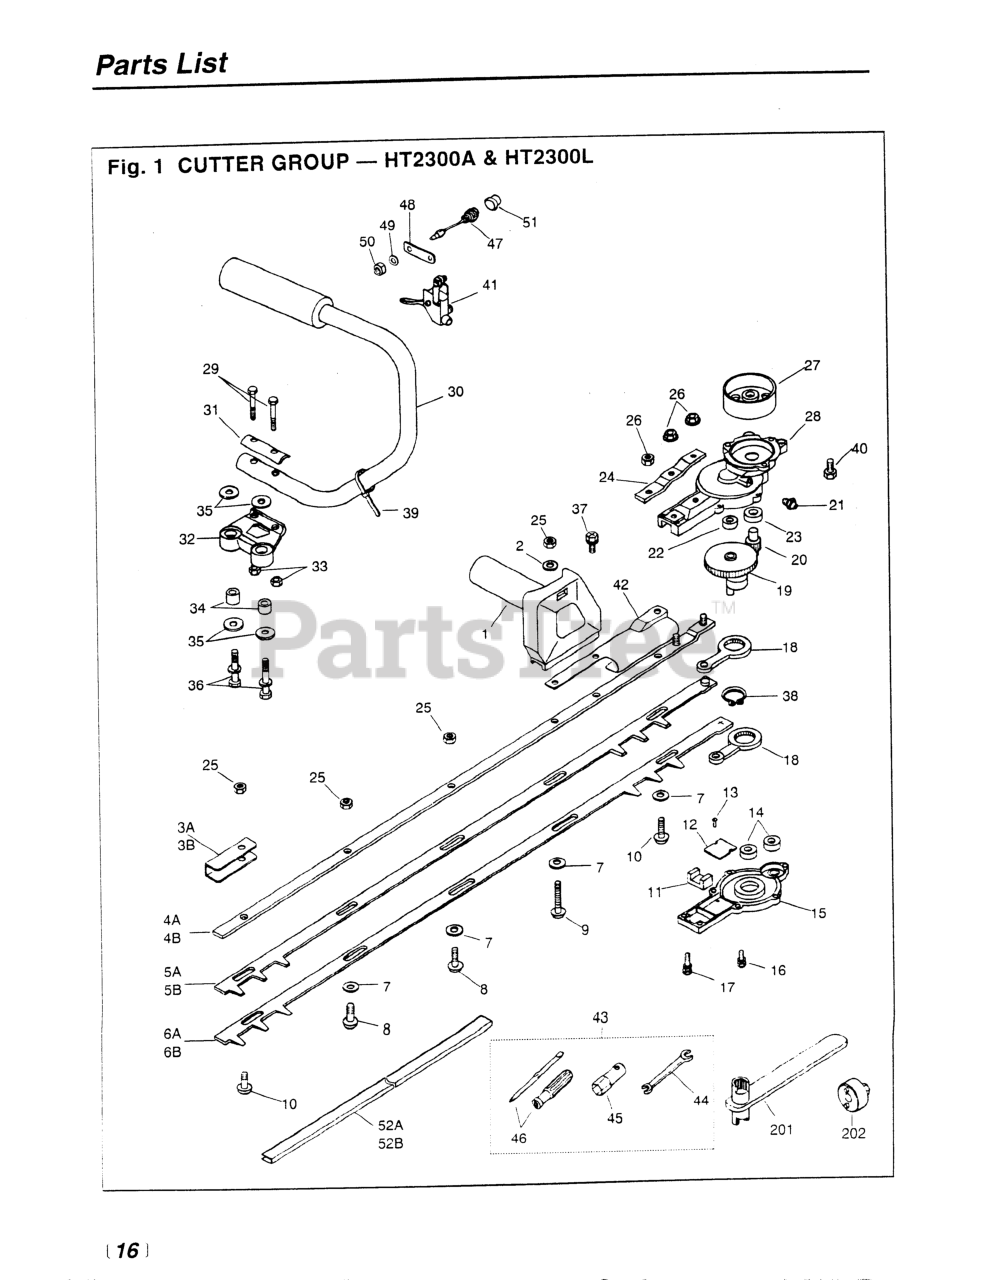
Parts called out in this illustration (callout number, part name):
1	HANDLE (RPLS -12100)
3B	REINFORCE
5B	BLADE, UPPER 40
6B	BLADE, LOWER 40
7	WASHER (RPLS 3873-11760)
11	FELT
12	PLATE
13	SCREW, M3 x 5
14	BEARING
15	CASE, LOWER
16	BOLT, M5 x 16
17	BOLT, M5 X 20
18	ROD
19	GEAR COMPLETE
20	PINION
21	FITTING, GREASE
22	BEARING
23	BEARING
24	PLATE (RPLS 3880-11130)
25	NUT, M6
26	NUT
27	DRUM, CLUTCH
28	CASE, UPPER (RPLS -11110)
29	BOLT, M5X30 (RPLS -50350)
30	HANDLE, LEFT
32	BRACKET
33	NUT (RPLS 3873-14470)
37	BOLT
38	RING, SNAP, M25 X 1.2
39	BAND, CABLE
40	BOLT, M6 X 14
41	LEVER ASSEMBLY
42	PROTECTOR
43	TOOL SET
44	SPANNER, 8 X 10 (RPLS 2540- )
45	SOCKET, HEX, 3/4
46	SCREWDRIVER
48	PLATE
49	WASHER
50	NUT
51	CAP
52B	COVER, BLADE (40
202	WRENCH (TOOL)
